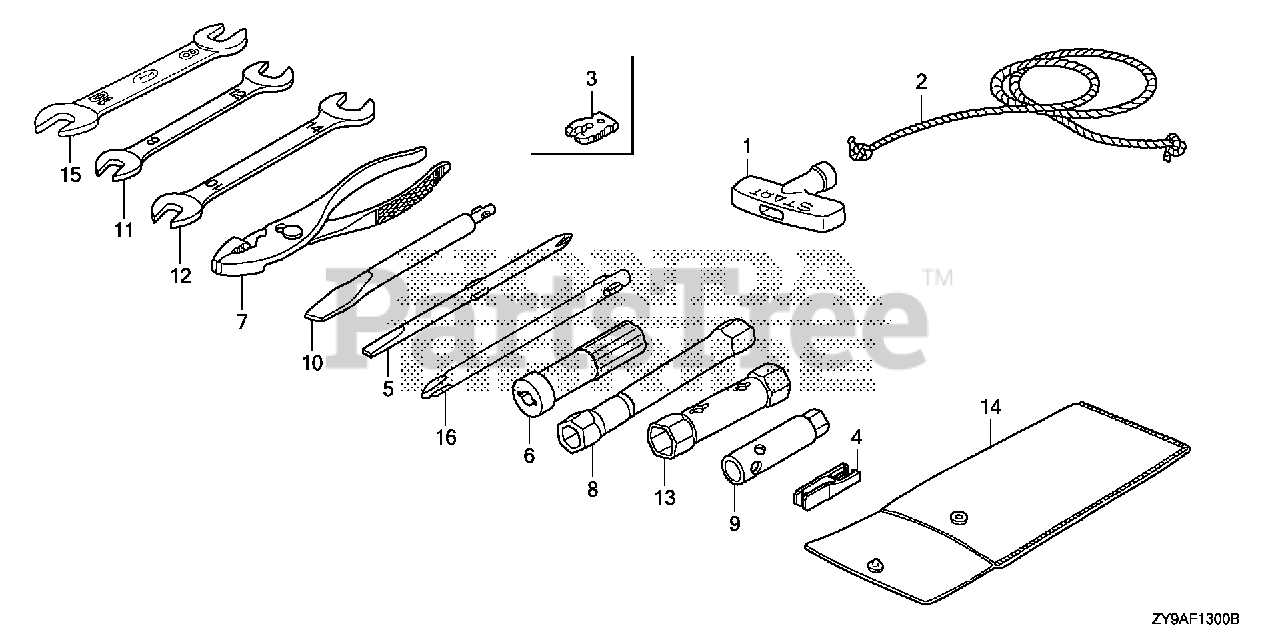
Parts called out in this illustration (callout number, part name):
1	GRIP, STARTER
2	ROPE, RECOIL STARTER (1300MM)
4	PULLER, MINI FUSE (SUMITOMO)
6	GRIP, SCREW DRIVER
8	WRENCH, PLUG
13	WRENCH, BOX (P18X19)
14	BAG, TOOL
15	SPANNER (8X10)
16	SCREWDRIVER 1, PHILLIPS (NO.2)
